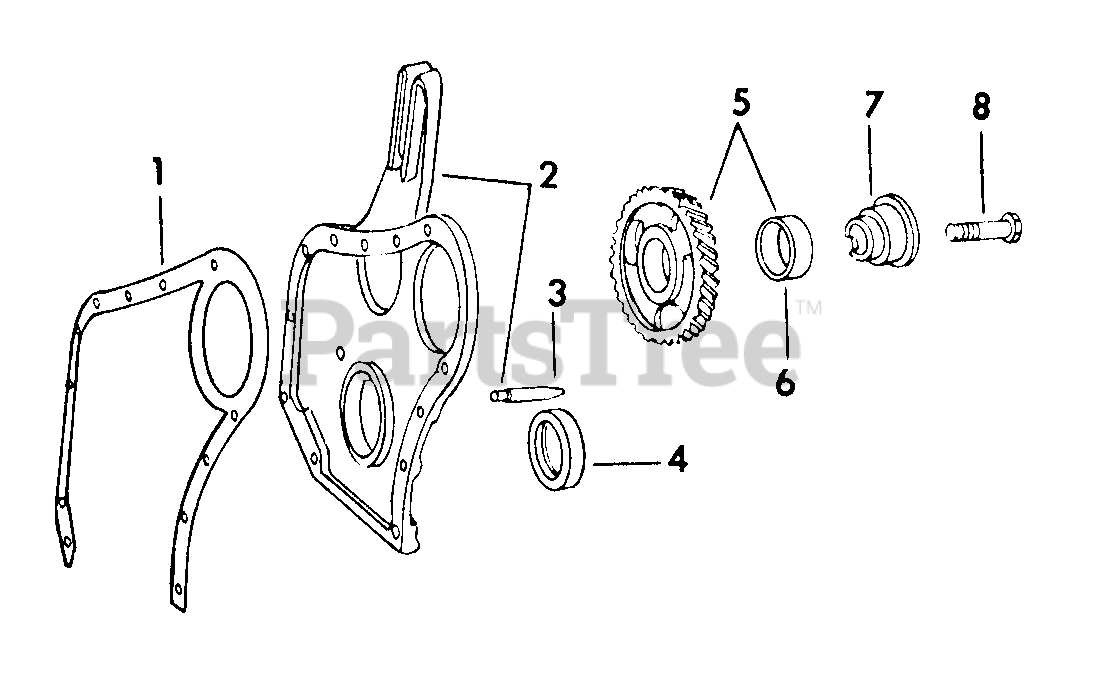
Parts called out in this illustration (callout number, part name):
1	GASKET CRANKCASE FRONT COVER
2	COVER ASSY, CRANKCASE FRONT
3	POINTER, TIMING
4	SEAL W/RING, CRANKCASE FRONT COVER OIL
5	GEAR W/BUSHING, IDLER
6	BUSHING, IDLER GEAR
7	SHAFT, IDLER GEAR
8	BOLT, IDLER GEAR SHAFT
